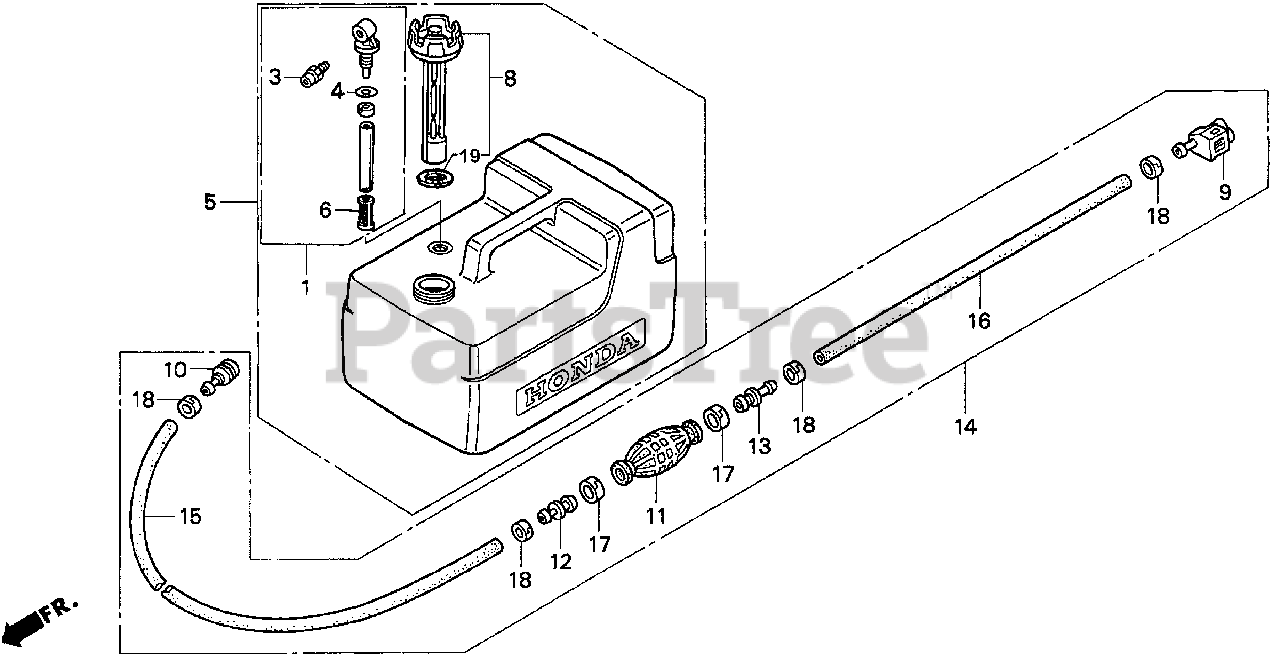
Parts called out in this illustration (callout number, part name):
1	JOINT ASSY., FUEL
3	FITTING, QUICK DISCONNECT
4	O-RING
5	TANK ASSY., FUEL
6	FILTER, FUEL
8	CAP, FUEL FILLER
9	CONNECTOR ASSY. A, FUEL
10	CONNECTOR, FUEL
11	PRIMER BULB
12	VALVE, IN.
13	VALVE, OUTLET
14	TUBE ASSY., FUEL
15	TUBE, FUEL LONG (7.5X2000)
16	TUBE, FUEL SHORT
17	BAND, TUBE CLIP (20MM)
18	BAND, TUBE CLIP (12.5MM)
19	GASKET, FUEL CAP
